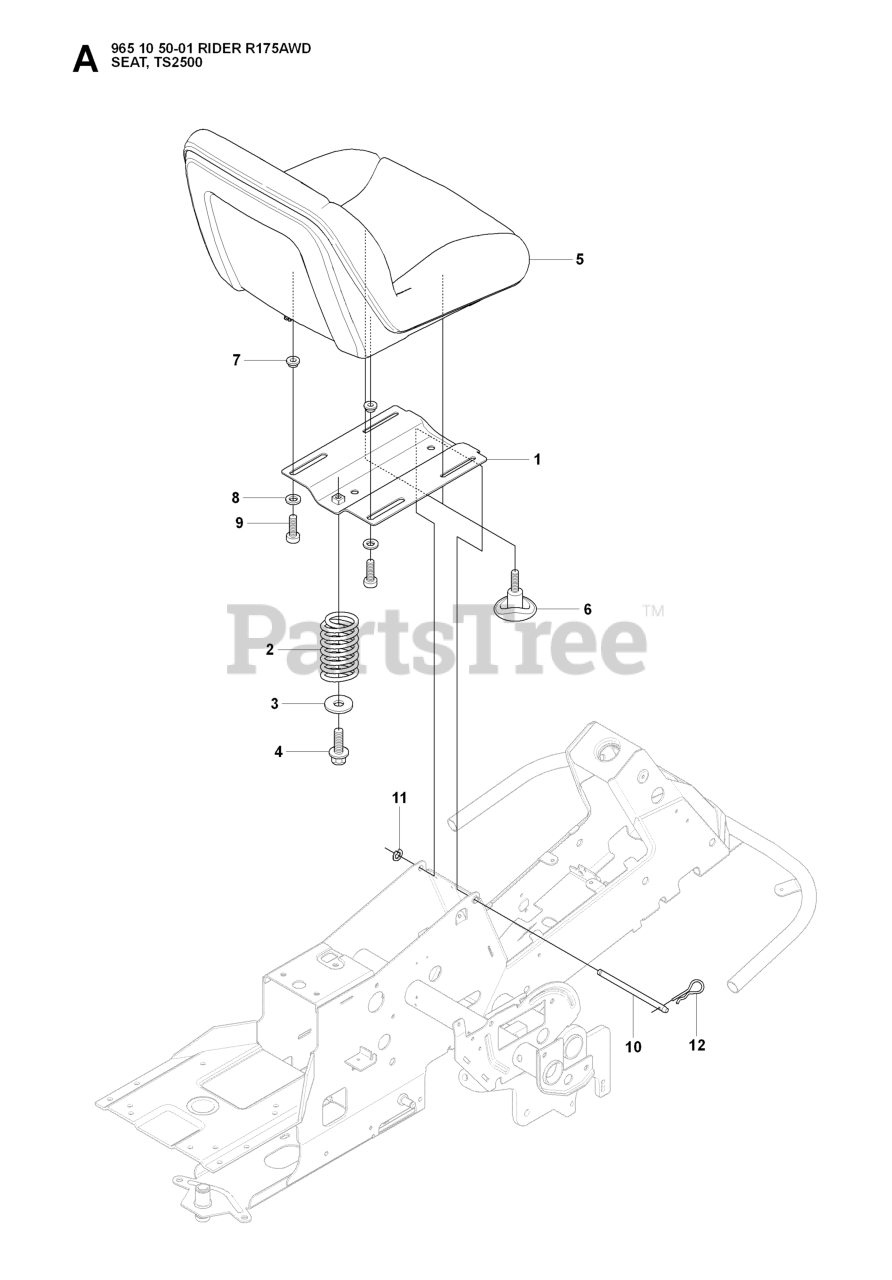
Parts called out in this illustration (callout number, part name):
1	SEAT BRACKET
2	SEAT SPRING
4	Screw M10x25
5	SEAT
6	ADJUSTING KNOB
11	RETAINING RING SGA 10
